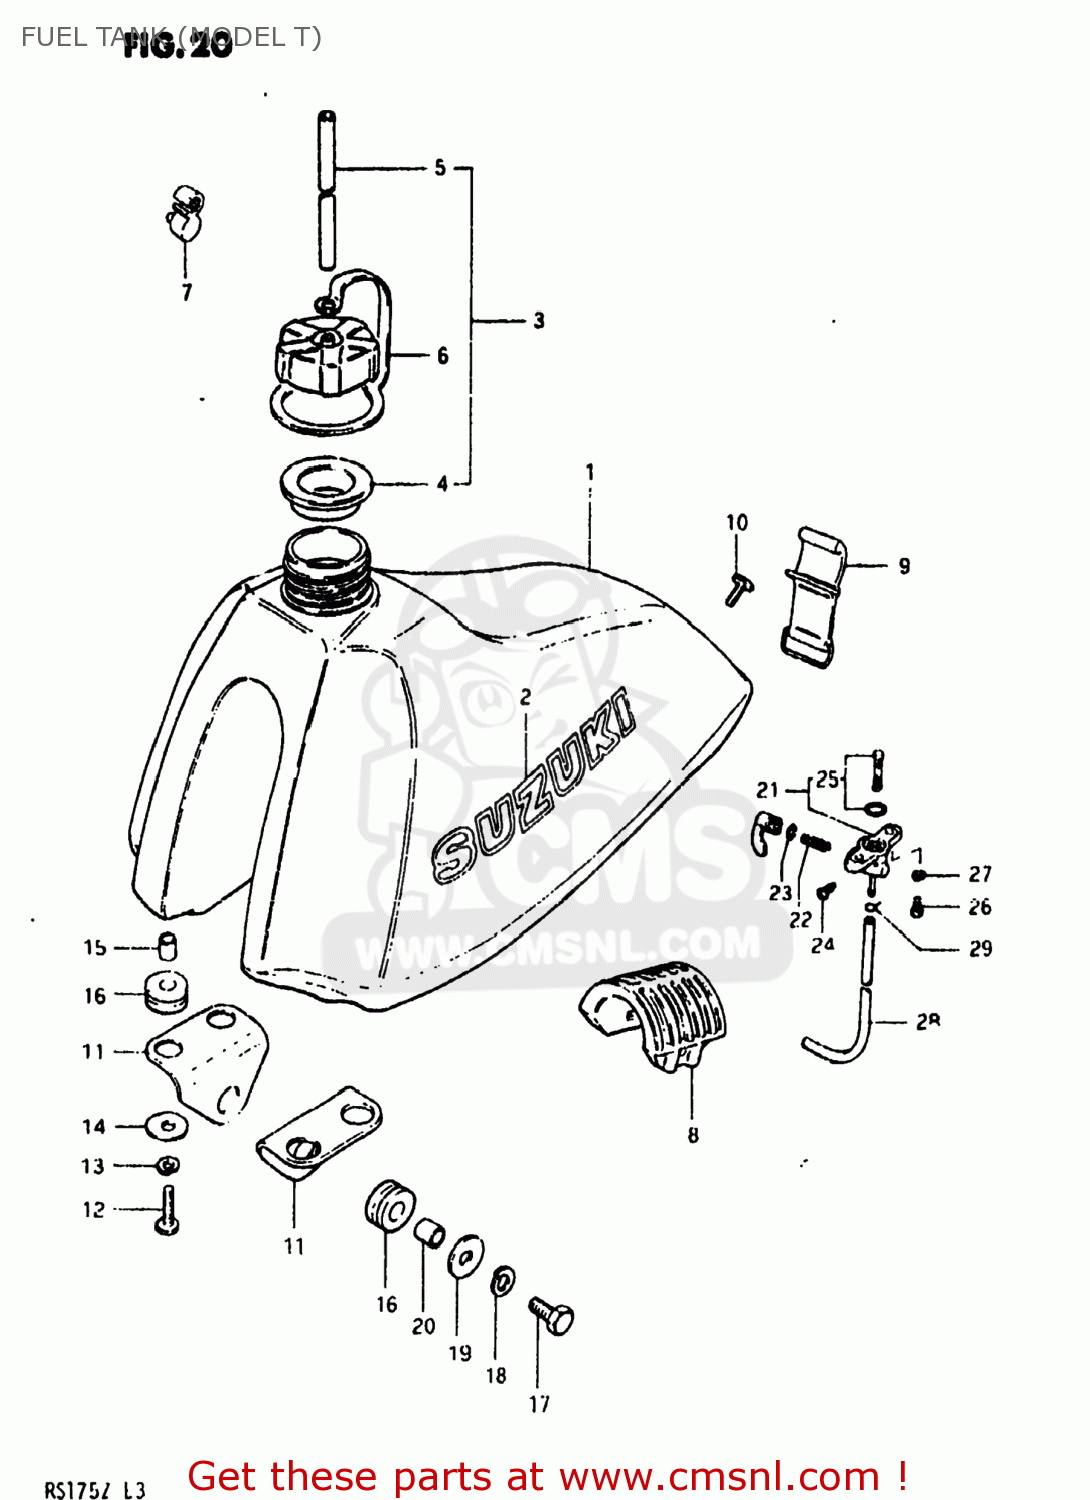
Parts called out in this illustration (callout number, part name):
1	TANK ASSEMBLY,FUEL
2	EMBLEM
3	CAP SET,FUEL TANK
4	GASKET,FUEL TANK CAP (NAS)
5	HOSE
6	BAND,FUEL TANK CAP
7	CLAMP,BREATHER HOSE
8	CUSHION,FUEL TANK
9	BAND
10	SCREW(6X18)
11	BRACKET,FUEL TANK,LOWER
12	SCREW
13	LOCK WASHER
14	WASHER (6.5X24X1.6)
15	SPACER(6.8X12X11)
16	CUSHION
17	BOLT (8X30)
18	LOCK WASHER
19	WASHER (8.2X24X1.6)
20	SPACER (8.8X12X11)
21	COCK ASSEMBLY,FUEL
22	SPRING,FUEL COCK VALUE
23	O RING,LEVER
24	SCREW
25	FILTER SET FUEL
26	SCREW
27	LOCK WASHER
28	HOSE
29	CLAMP
